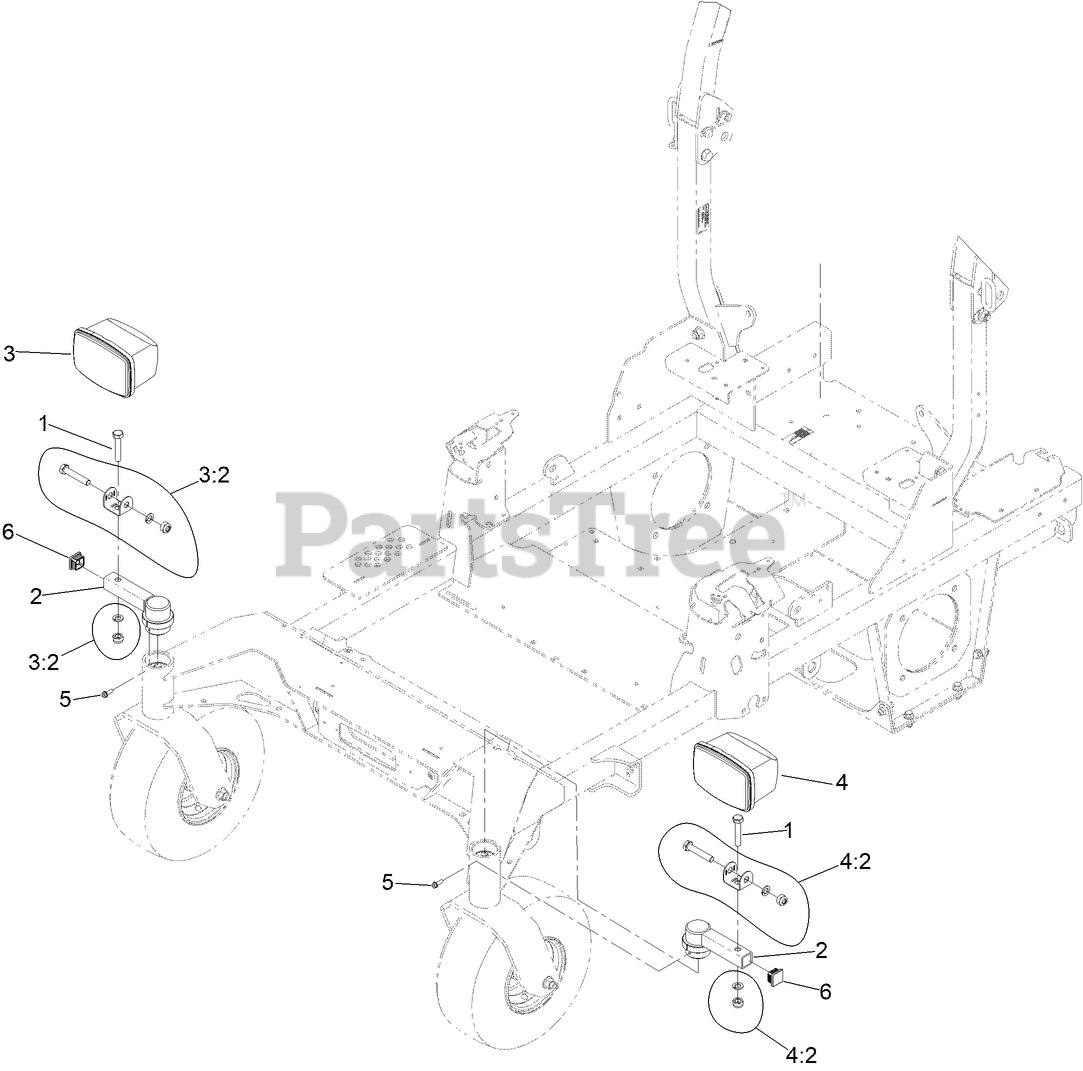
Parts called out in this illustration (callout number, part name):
1	SCREW-HH
2	LIGHT MOUNT ASM [RED]
3	RH LIGHT ASM
3:2	LIGHT MOUNT KIT
4	LH LIGHT ASM
4:2	LIGHT MOUNT KIT
5	SCREW-HWH
6	CAP, SQUARE-END
